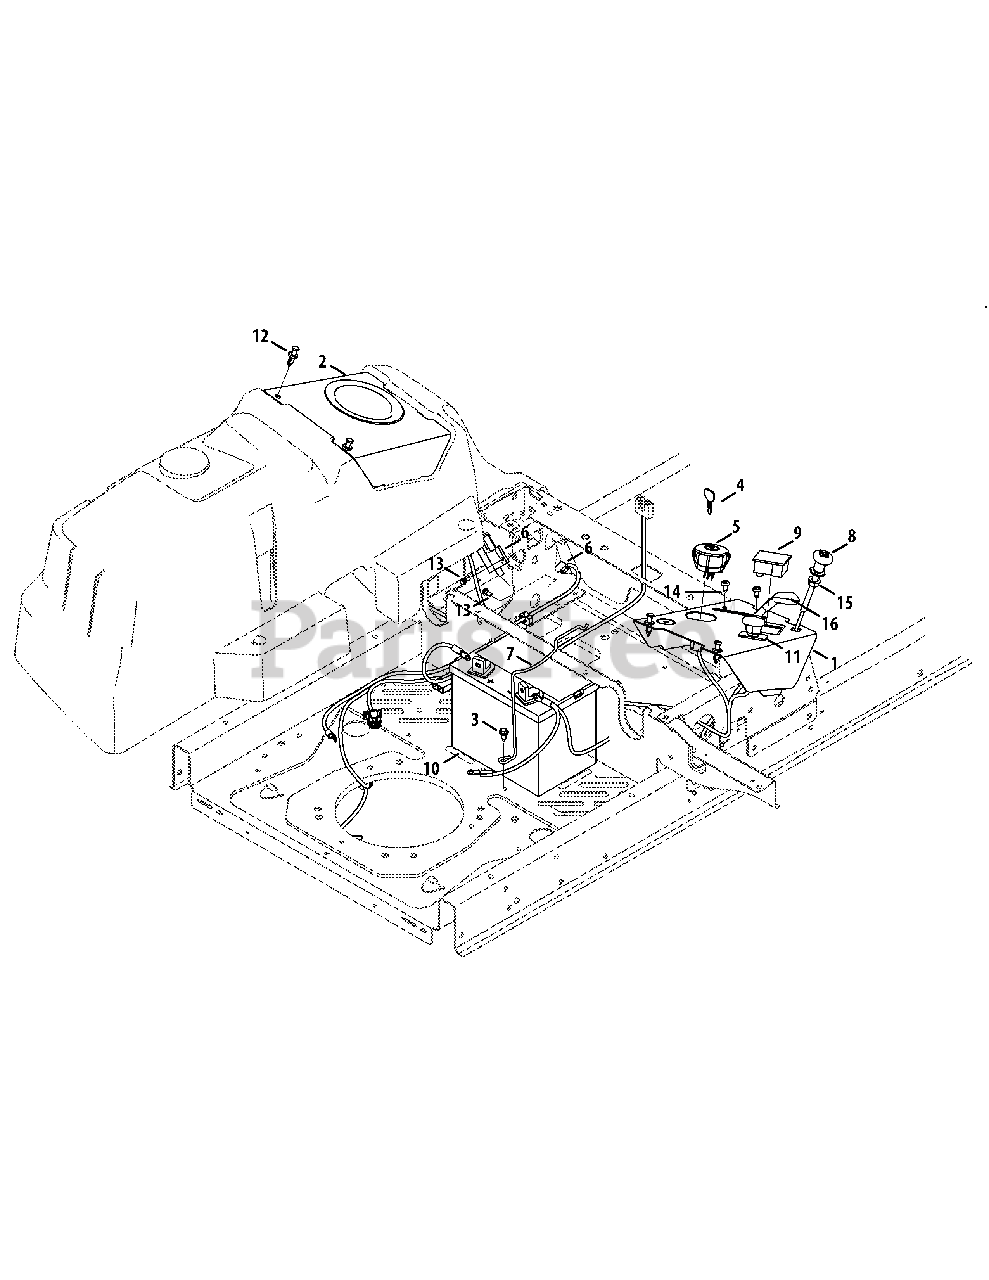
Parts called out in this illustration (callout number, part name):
1	Console Cover, RH
2	Console Cover, LH
3	Hex Washer Screw, 1/4-20 x .625
4	Key, Assembly
5	Key Switch
6	Interlock Switch
8	Choke Cable
9	Hour Meter/Service Minder
11	Electric PTO Switch
12	Plastic Rivet
13	Shoulder Screw, #10-32 x .500
14	Screw, 1/4-20 x .50
15	Flange Lock Nut, 3/8-16
16	Throttle Cable, Command
